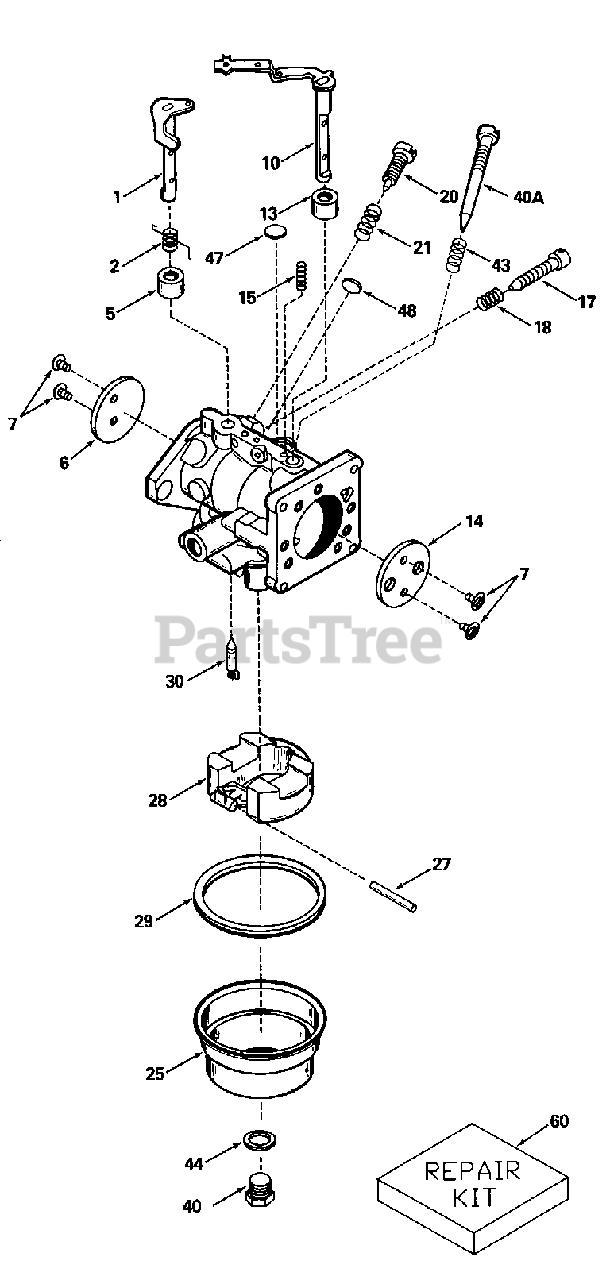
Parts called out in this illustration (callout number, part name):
1	Throttle Shaft & Lever Ass'y.
2	Throttle Return Spring
5	* Dust Seal (Throttle)
6	Throttle Shutter
7	Throttle & Choke Shutter Screw
10	Choke Shaft & Lever Ass'y.
13	* Dust Seal (Choke)
14	Choke Shutter
15	Choke Positioning Spring
17	Idle Speed Screw
18	Tension Spring
20	* Idle Mixture Screw
21	Idle Tension Spring
25	Float Bowl
27	* Float Shaft
29	* Float Bowl "O" Ring
30	* Inlet Needle
40	Bowl Nut
40A	High Speed Jet
43	High Speed Mixture Spring
44	* Bowl Nut Washer
47	* Welch Plug
48	* Welch Plug
60	Repair Kit (Incl. items marked PK in notes) Incl. (1) each of part #'s2711 2, 632039, 632443, 632444,632446, 632 447, 632448
